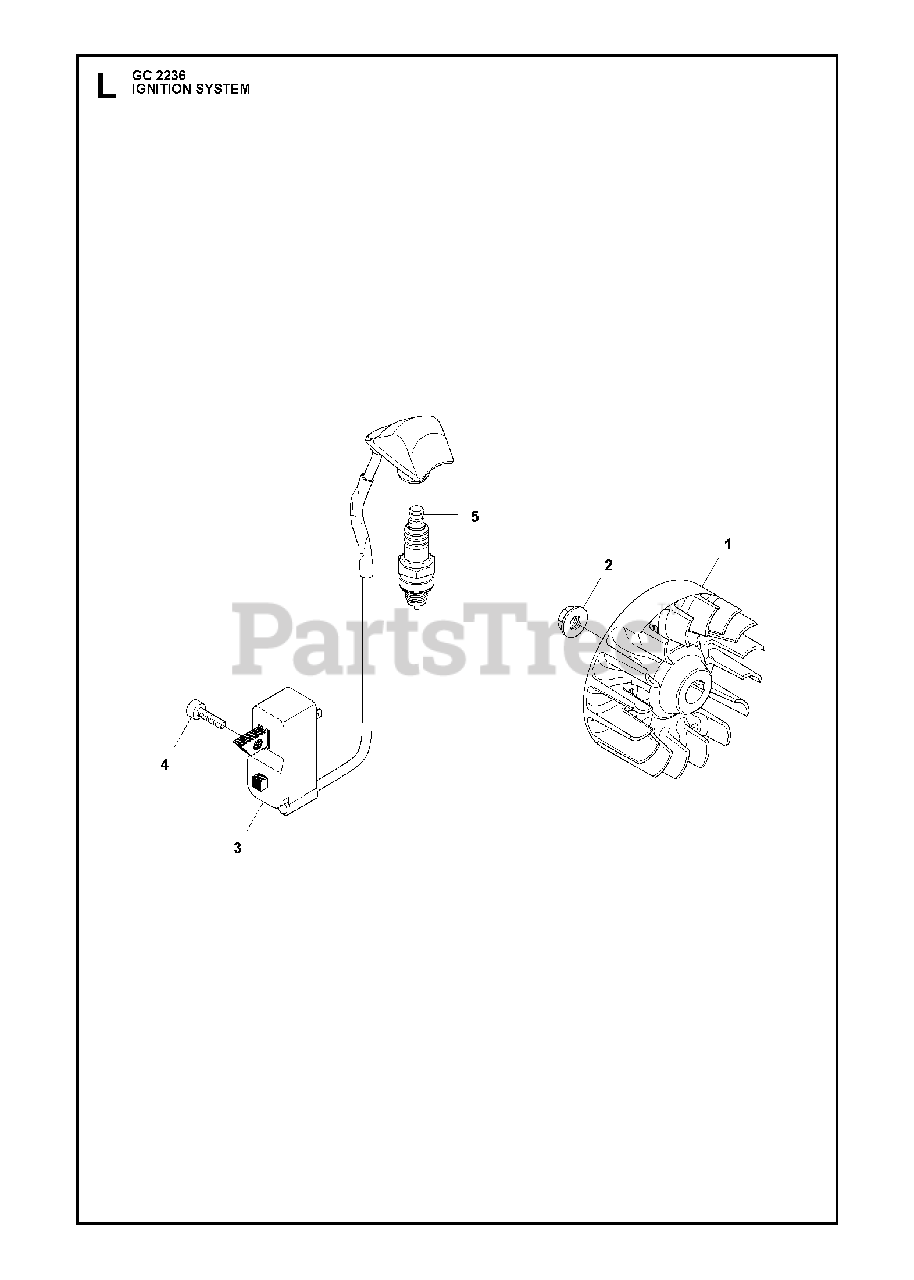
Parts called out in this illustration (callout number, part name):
1	FLYWHEEL
2	FLANGE NUT
3	IGNITION MODULE OPS
5	SPARK PLUG RCJ6Y NLA
